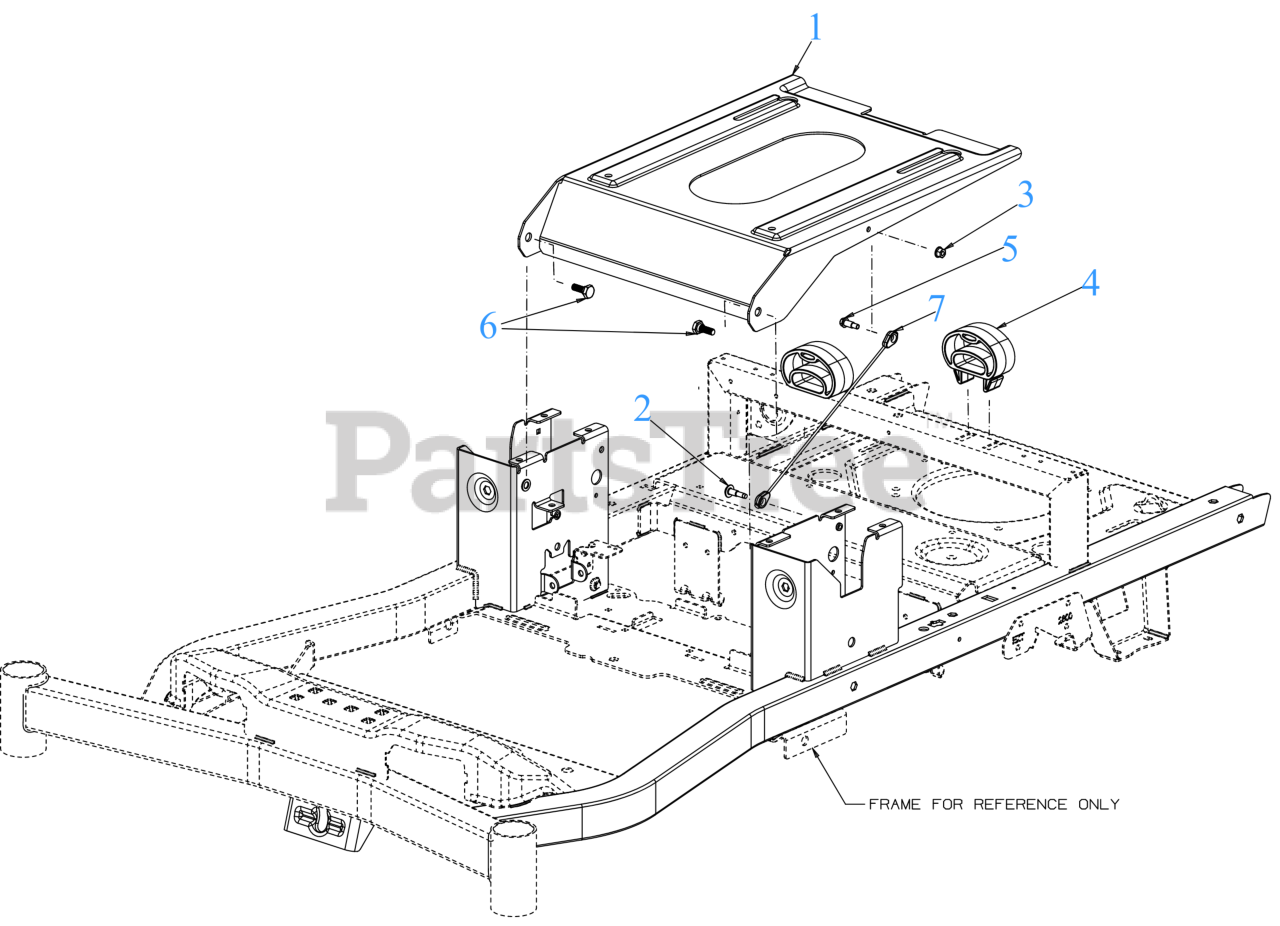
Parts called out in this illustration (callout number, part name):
1	SEAT BASE PLATE
2	BOLT 1/4-20
3	LOCK NUT 1/4
4	POLYMER SEAT SPRING
5	SHOULDER SCREW
6	SHOULDER SCREW .44DIAx.18 5/16-18
7	SEAT BASE CABLE
